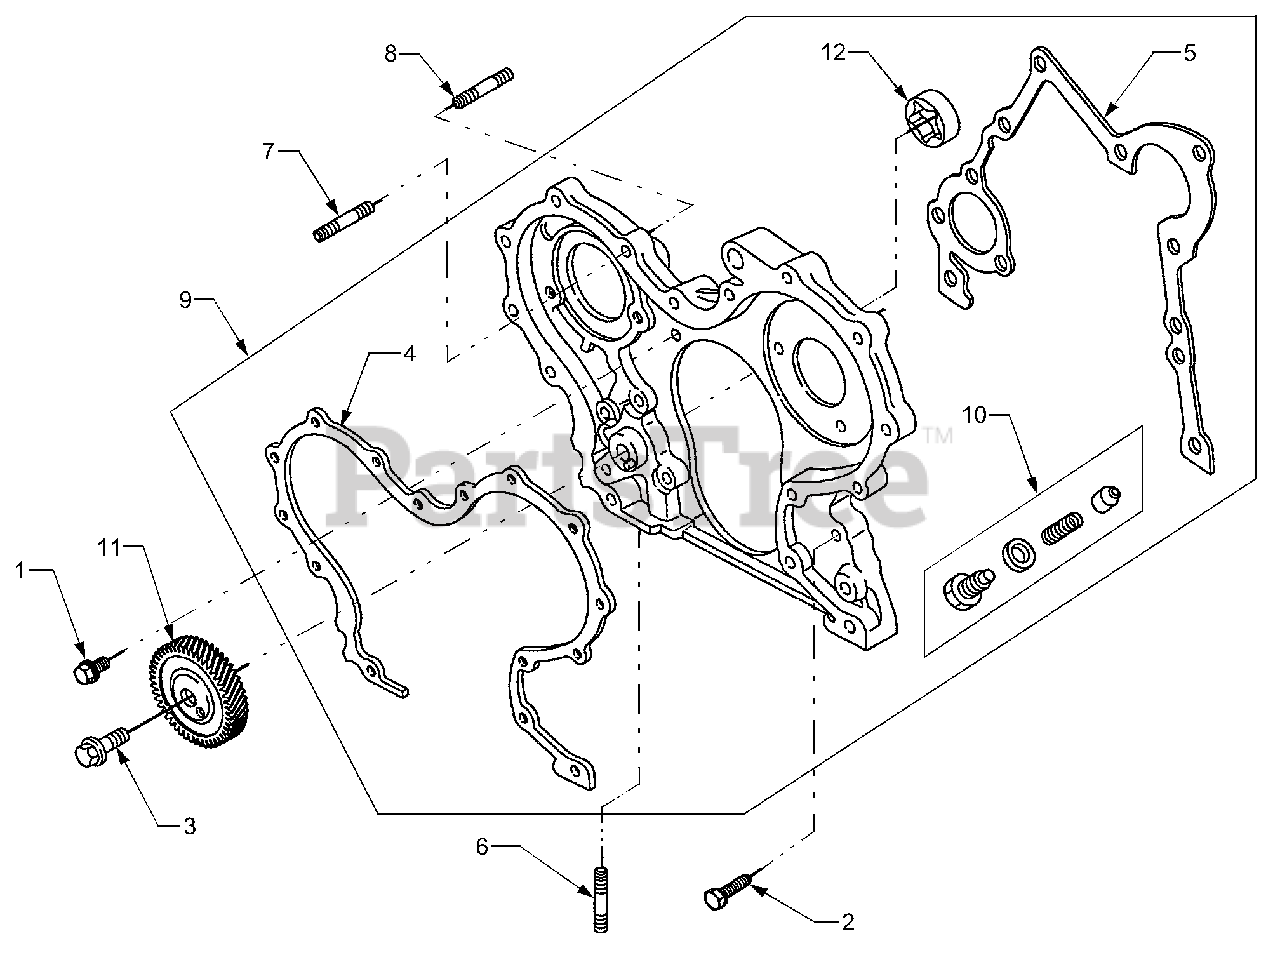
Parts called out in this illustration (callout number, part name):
1	Screw, Hex, 6mm
2	Screw, Hex, 6mm
3	Screw, Hex, 8mm
4	Gasket, Gear Cover
5	Gasket, Gear Cover
6	Stud, Metric
7	Stud, Metric
8	Stud, Metric
9	Housing, Gear
10	Valve, Oil Relief
11	Gear, Oil Pump Drive
12	Pump. Oil
